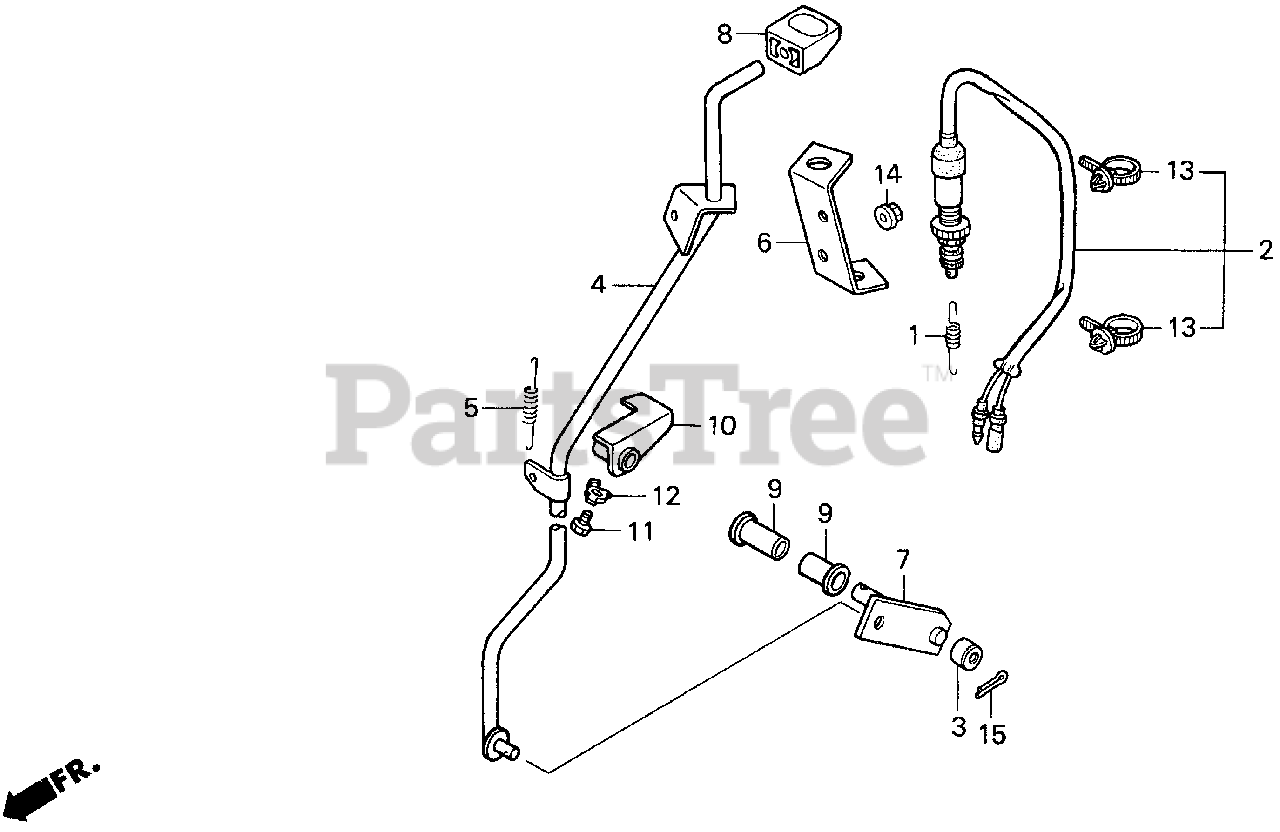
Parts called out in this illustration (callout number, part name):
1	SPRING, CONTROL LEVER RETURN
2	SWITCH ASSY., PARKING BRAKE
3	COLLAR, PUSH ROD
4	LEVER, PARKING BRAKE
5	SPRING, PARKING BRAKE LEVER
6	BRACKET, PARKING BRAKE LEVER
7	ARM, PARKING BRAKE
8	KNOB, PARKING BRAKE
9	BUSH, PARKING BRAKE
10	ARM, PARKING BRAKE STOPPER
11	BOLT, HEX. (6MM)
12	WASHER, LOCK (6MM)
13	BAND, WIRE HARNESS (110MM) (BROWN)
14	NUT, FLANGE (6MM)
15	PIN, COTTER (2.5MM)
